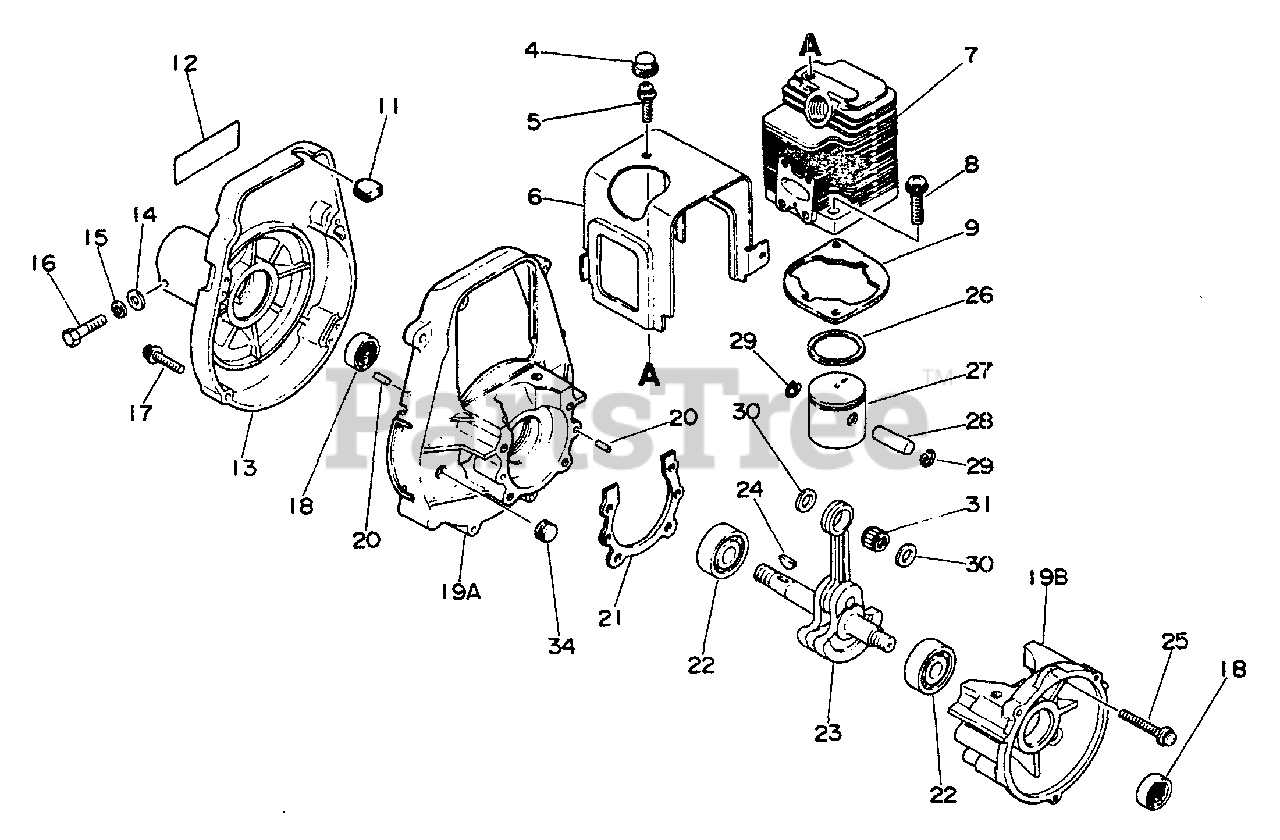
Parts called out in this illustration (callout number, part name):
5	SCREW - 5X10
6	SHIELD, CYLINDER
7	CYLINDER
8	SCREW - 6X20
9	GASKET, CYLINDER
11	PLUG
12	LABEL - MODEL
13	CASE, STARTER
14	WASHER - 6
15	LOCKWASHER - 5
16	BOLT - 5X25
17	SCREW - 4X20
18	SEAL, OIL
19	CRANKCASE KIT
19A	CRANKCASE KIT
19B	CRANKCASE KIT
20	PIN - LOCATING
21	GASKET, CRANKCASE
22	BEARING, BALL - 6201
23	CRANKSHAFT ASSY
25	SCREW - 5X30
26	RING, PISTON
27	PISTON
28	PIN, PISTON
29	RING, RETAINING
30	SPACER, PISTON
31	BEARING, NEEDLE - 8
34	PLUG
